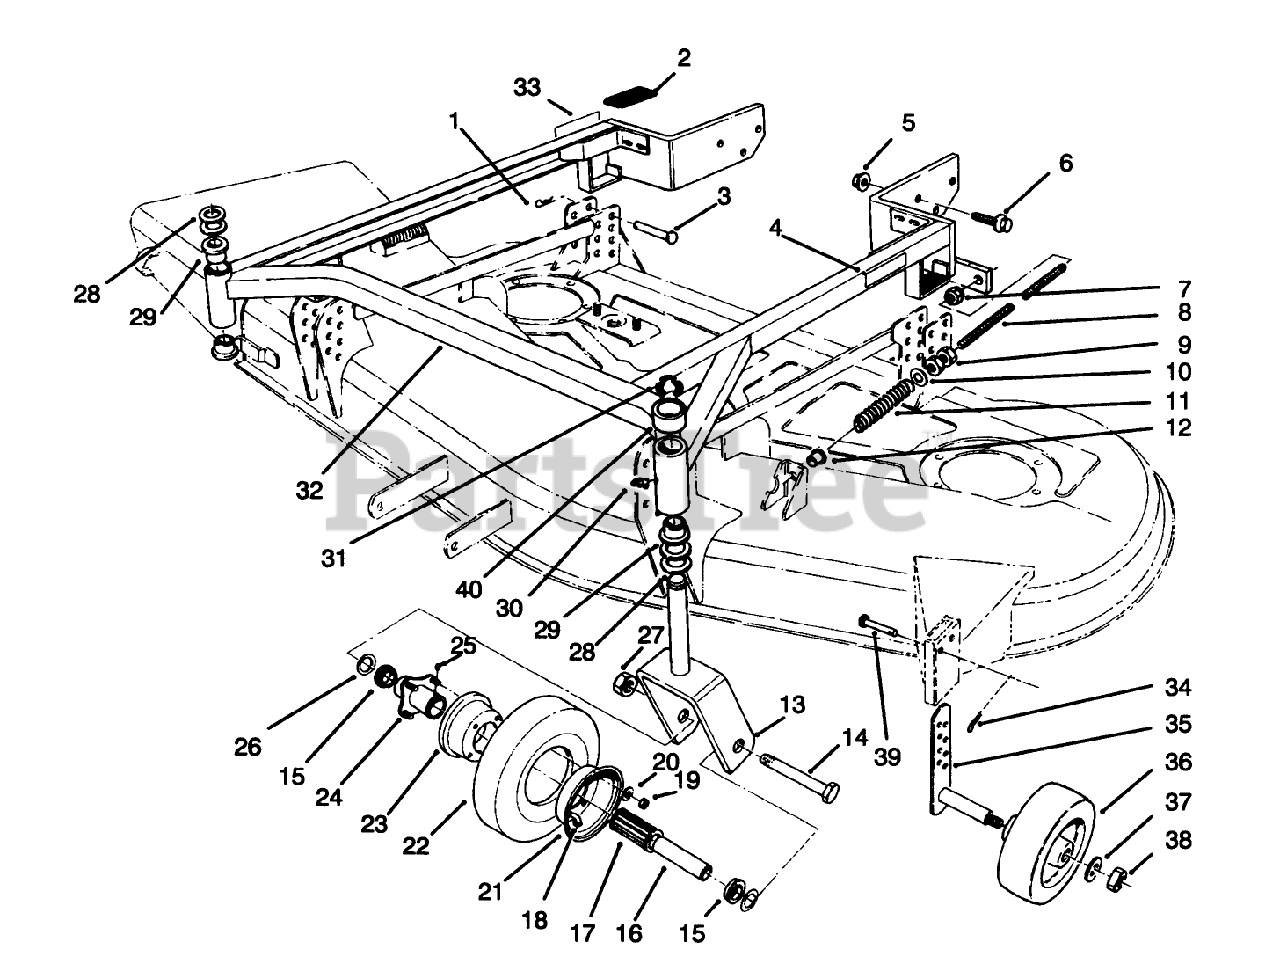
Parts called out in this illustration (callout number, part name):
1	PIN-HAIR
2	CUSHION-RUBBER
3	PIN-CLEVIS
4	DECAL-HOC, LH
5	NUT-HF
6	SCREW-HHF
7	NUT-LOCK, NI
8	SHAFT-ADJUSTING
9	NUT-JAM
10	WASHER
11	SPRING
12	BUSHING-FLANGE
13	Fork
14	SCREW-HH
15	BEARING-OUTSIDE
16	SPANNER-TIRE
17	BEARING-ROLLER
18	TUBE-INNER (W/VALVE)
19	NUT-HEX
20	WASHER-LOCK
21	MALE WHEEL HALF
23	FEMALE WHEEL HALF
24	HUB-CENTER
25	FITTING-GREASE
26	WASHER-FLAT
27	NUT-HEX
28	WASHER-THRUST
29	Bushing
30	FITTING-GREASE
31	RING-RETAINING
32	Frame-Carrier (Incl. Ref. #30)
33	DECAL-HOC, RH
34	PIN-HAIR
35	GAGE-WHEEL
36	WHEEL-GAGE
37	WASHER-FLAT
38	NUT-LOCK, NI
39	PIN-CLEVIS
40	SPACER-CASTOR
